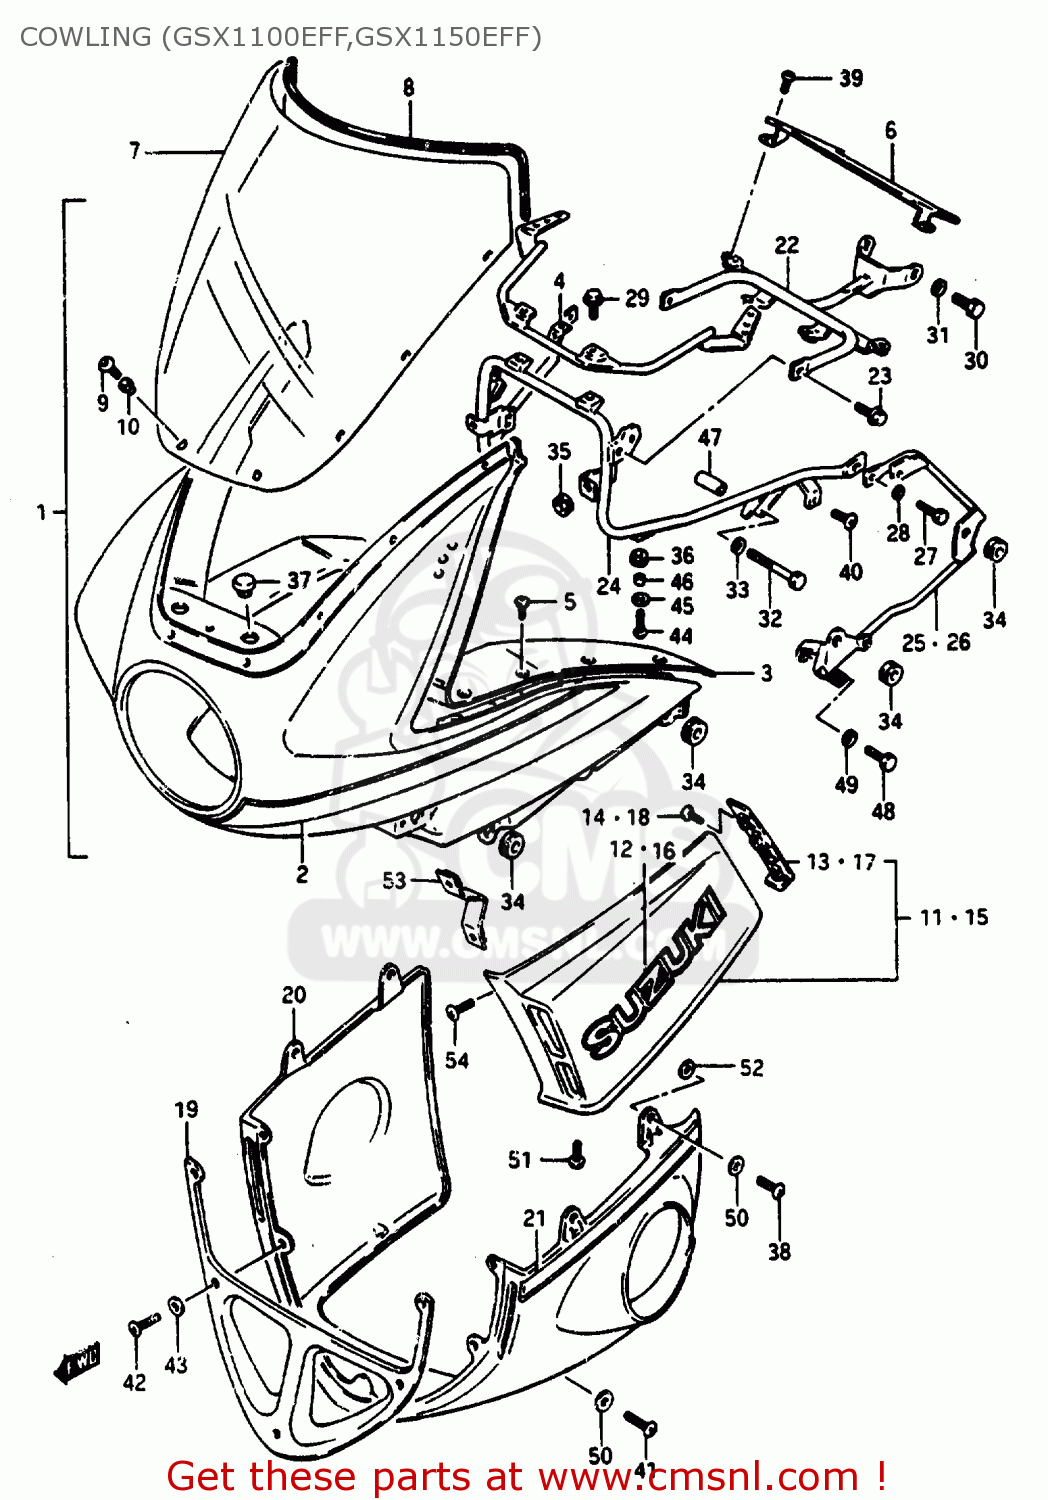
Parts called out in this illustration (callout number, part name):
1	COWLING ASSY (WHITE/RED)
2	TAPE SET
3	PANEL,COWLING
4	BRACE,COWLING BODY
5	SCREW, PANEL
6	COVER,METER,REAR
7	SCREEN
8	MOLDING
9	SCREW(5X20)
10	CUSHION
11	COVER,RH
12	EMBLEM
13	PANEL,COWL SIDE COVER RR RH
14	SCREW
15	COVER,LH
16	EMBLEM
17	PANEL,COWLING SIDE COVER
18	SCREW
19	COVER, LOWER (RED)
20	COVER (WHITE)
21	TAPE SET.
22	BRACE,COWLING,FRONT
23	BOLT
24	BRACE,COWL RR
25	BRACE,COWLING SIDE,RIGHT
26	BRACE,COWLING SIDE,LEFT
27	BOLT 6X16
28	WASHER,LOCK
29	BOLT
30	BOLT
31	WASHER,LOCK,8.
32	BOLT
33	WASHER,LOCK,8.
34	CUSHION
35	CUSHION
36	CUSHION
37	PLUG(OD:22)
38	SCREW, CENTER
39	SCREW 5X10
40	SCREW 6X12
41	SCREW, CENTER
42	SCREW
43	WASHER
44	SCREW, CENTER
45	WASHER(6.5X18X1)
46	SPACER (6.1X9X9)
47	SPACER (8.6X13.8X35)
48	BOLT
49	WASHER,LOCK,8.
50	WASHER
51	SCREW
52	WASHER(6X13X2)
53	BRACE,SIDE,FRONT
54	SCREW
